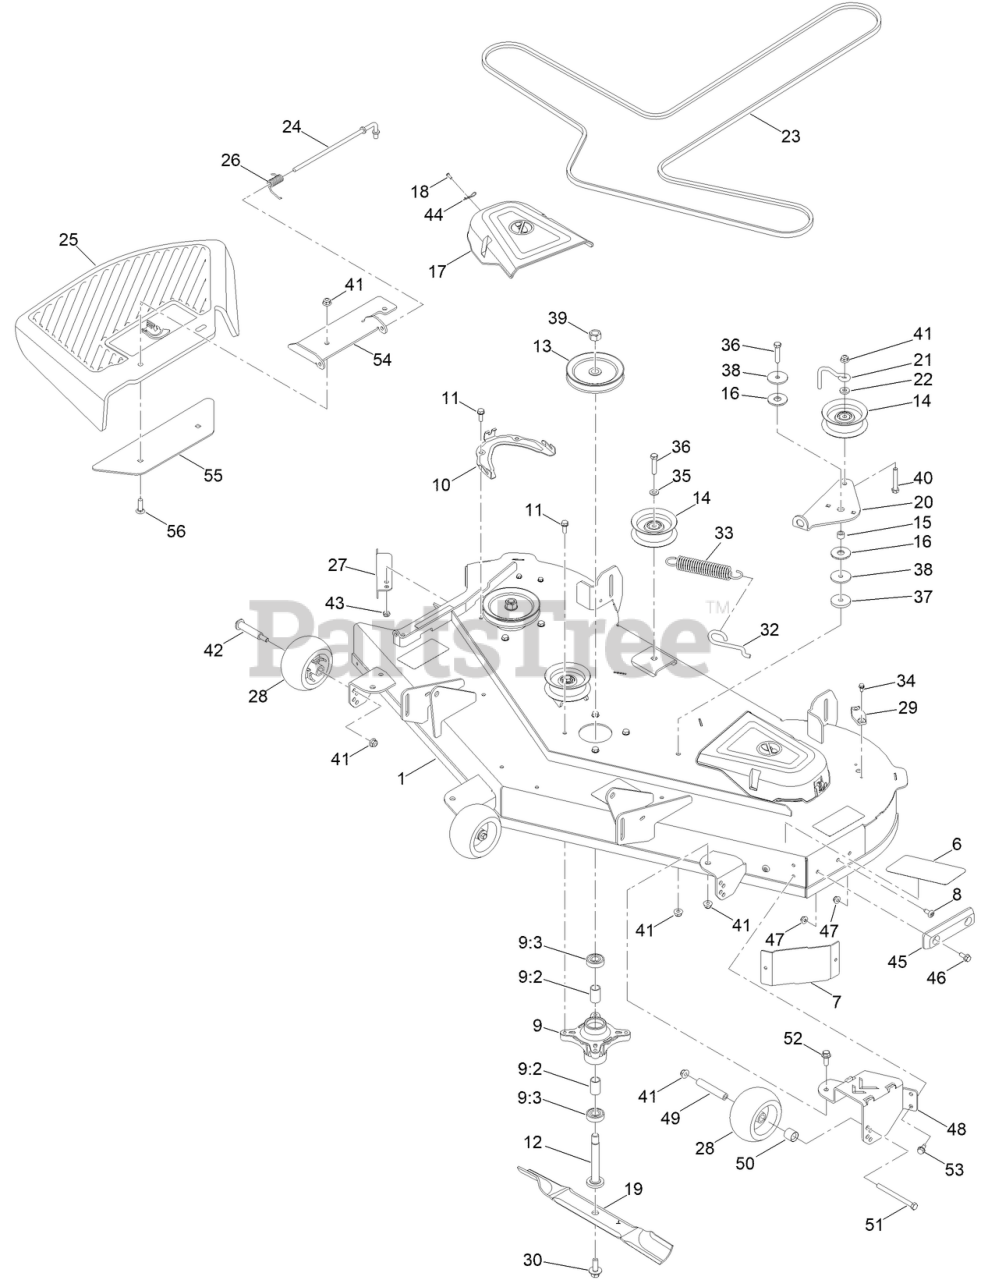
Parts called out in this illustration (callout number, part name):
1	54 IN DECK AND DECAL ASM
6	DECAL-DECK 54in
7	BAFFLE-CORNER
9	SPINDLE ASM
9:2	SPACER
9:3	BEARING-BALL
10	BRACKET-COVER, BELT
11	SCREW-TAPTITE
12	SHAFT-SPINDLE
13	PULLEY ASM
14	PULLEY-IDLER, FLAT
15	SPACER
16	WASHER-FRICTION, COMPOSITE
17	COVER-BELT
18	SCREW
19	BLADE-HI LIFT
20	ARM-IDLER
21	GUIDE-BELT, IDLER
22	SPACER-HUB, BLOWER
23	BELT-V (A SEC, 145.5 EL)
24	ROD-PIVOT
25	DEFLECTOR-DISCHARGE
26	SPRING-TORSION
27	BAFFLE-CUTOFF
28	ROLLER-SCALP, ANTI
29	COVER-WASHOUT PORT
30	BOLT-BLADE, SEMS
32	SPRING-RETURN, HOOK
33	SPRING-EXTENSION
34	SCREW-HWH
35	WASHER-FLAT
36	SCREW-HH
37	WASHER-PLAIN
38	WASHER-REBOUND
39	NUT-HEX
40	SCREW-HH
41	NUT-HF, NI
42	BOLT-SHOULDER
44	PIN-HAIR
45	BUMPER-NYLON
46	SCREW-HHF
47	NUT-HF
48	PLATE-STEP
49	TUBE-SPANNER
50	SPACER-AXLE, REAR
51	SCREW-HH
52	SCREW-HHF
53	SCREW-HWHTF
54	BRACKET-DISCHARGE, TOP
55	SUPPORT-DEFLECTOR
56	SCREW-CARR
